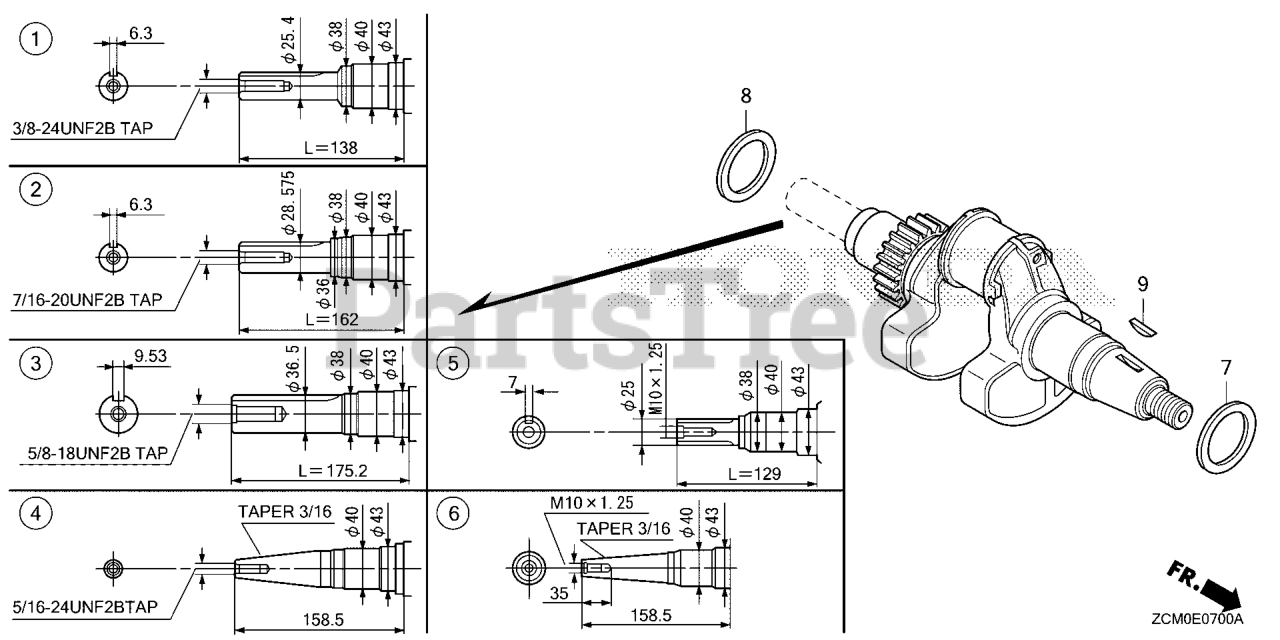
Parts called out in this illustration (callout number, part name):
4	CRANKSHAFT (L=158.5)
8	WASHER, CRANKSHAFT THRUST
9	KEY, SPECIAL WOODRUFF (25X18)
